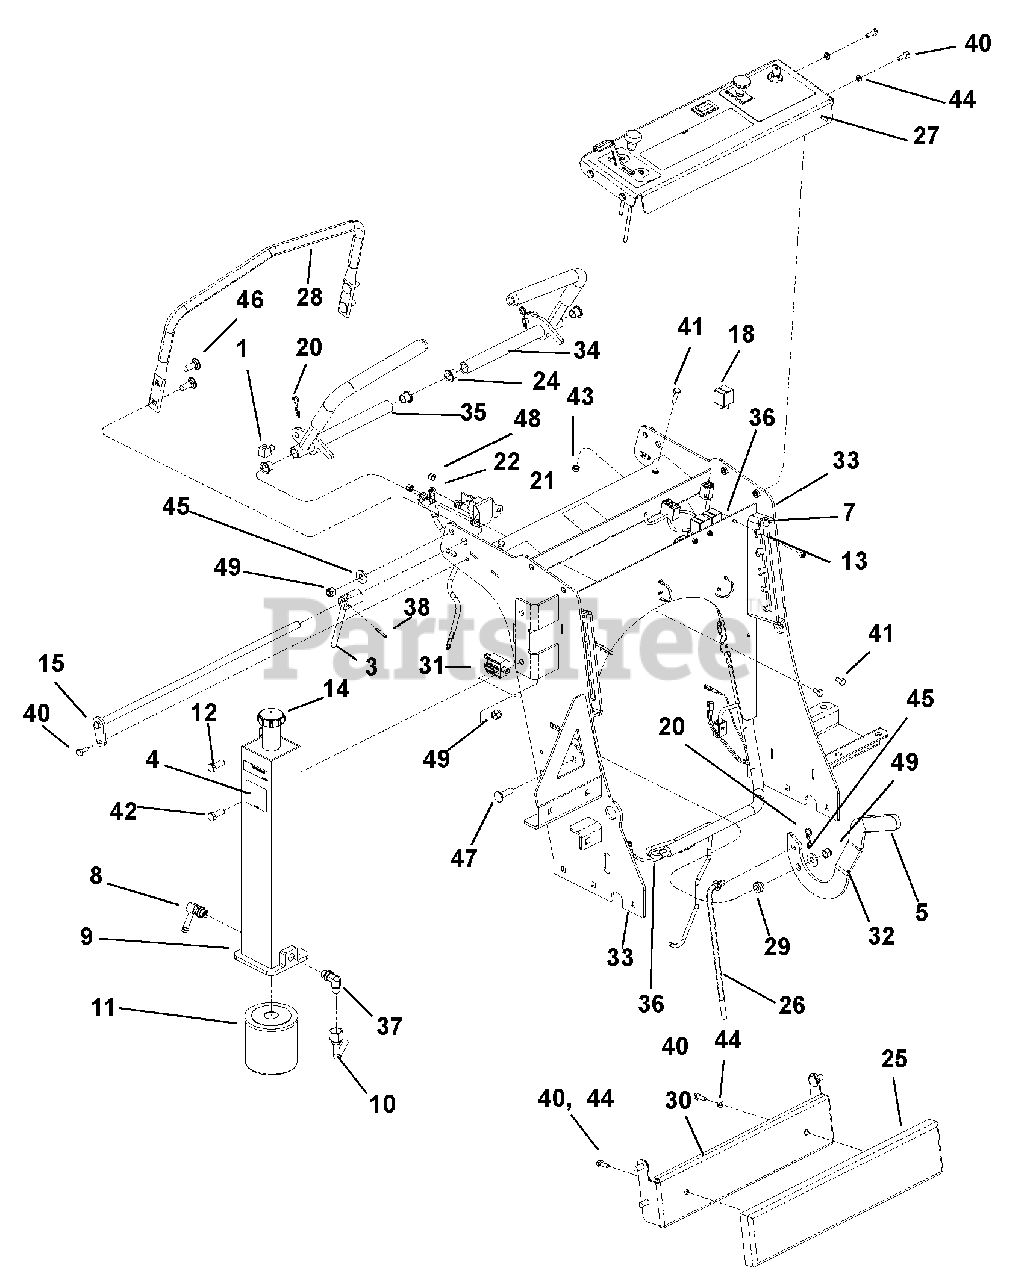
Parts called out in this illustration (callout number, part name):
1	Swivel Adjuster
2	Base, Lock Lever Y
3	Lever, Lock Y
4	Decal, Hydro Oil Specs.
5	Grip, PVC .250 x 1.00 x 3.63
6	Grip, Control
7	Screw, 8-32 x .50 Pan Phl Y
8	Fitting, 90 9/16 MOR x 3/8 HOSE
9	Weldment, Reservior Hydraulic
10	Elbow, Fitting
11	Filter, Oil
12	Decal, Warning - Hot Surfaces
13	Nut, 8-32 Elastic Stop
14	Cap, Filler Oil
15	Weldment, Pivot Rod Y
16	Decal, Warning, Slope
17	Decal, Directional Control
18	Relay, Iso Mini Elec.
19	Tie Wrap, Black
20	Pin, Hair Internal .09 x 1.65
21	Solenoid, 12 V Starter
22	Cable, 12" Starter
23	Decal, Patent Covered
24	Bearing, Flange .500 x .620 x .500
25	Pad, Thigh
26	Link, Brake
27	Assembly, Control Panel
28	Handle, Support
29	Bushing, Brake Pivot Y
30	Weldment, Thigh Pad Bracket
31	Switch, NO-NO-NC Grey Plunger
32	Brake Lever, Offset
33	Weldment, Console 34
34	Weldment, RH Control Lever
35	Weldment, LH Control Lever
36	Harness, Wiring
37	Adapter 2503-6-6
38	Pin, Spring 5/32 x 1
39	Bolt, Hex .25-20 x .50 Grade 5
40	Bolt, Hex .25-20 x .75 Grade 5
41	Bolt, 1/4-20 x 1.00 Hex 5 Y
42	Bolt-Hex .38-16 x 1.00 Grade 5
43	Nut, 1/4-20 STD HEX GR5 Y
44	Washer, Locking .25 x .062 Regular
45	Washer, Flat-Steel .438 x 1.00 x .083
46	Bolt, Round Head Square Neck .38-16 x 1.00 Grade 5
47	Bolt, Round Head Square Neck .38-16 x 1.25 Grade 5
48	Nut, Locking-Nylon .250-20
49	Nut, Locking-Nylon .38-16
